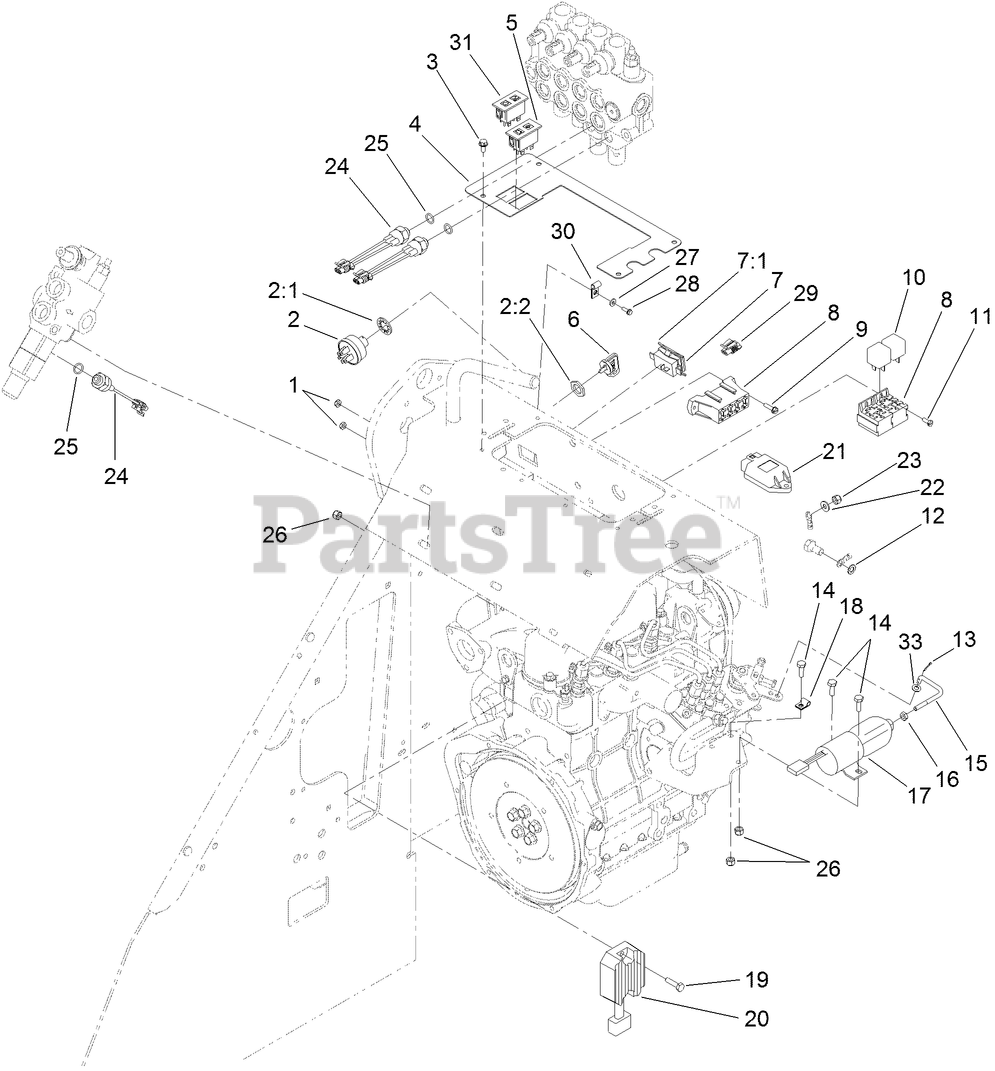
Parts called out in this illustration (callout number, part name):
1	NUT-LOCK, NI
2	Key Switch ASM
2:1	WASHER-TOOTH, INTERNAL
2:2	NUT-HH
3	SCREW-HWH
4	PLATE-COVER
5	LAMP-WARNING
6	KEY-IGNITION
7	HOUR METER ASM
7:1	CLIP-MOUNTING
8	HARNESS-WIRE
9	SCREW-HWH
10	RELAY
11	SCREW-SHH
12	WASHER-LOCK
13	PIN-COTTER
14	SCREW-HH
15	Rod-Linkage
16	NUT-JAM
17	SOLENOID
18	CLAMP-BODEN
19	SCREW-HH
20	REGULATOR ASM
21	CONTROLLER-GLOW
22	WASHER-SPRING
23	NUT-HEX
24	SWITCH-BALL
25	O-RING
26	NUT-LOCK, NI
27	WASHER-FLAT
28	SCREW-HWHTF
29	Connector-Female
30	CLIP-CLOSED, INSULATED
31	LAMP-WARNING
33	WASHER-NYLON
